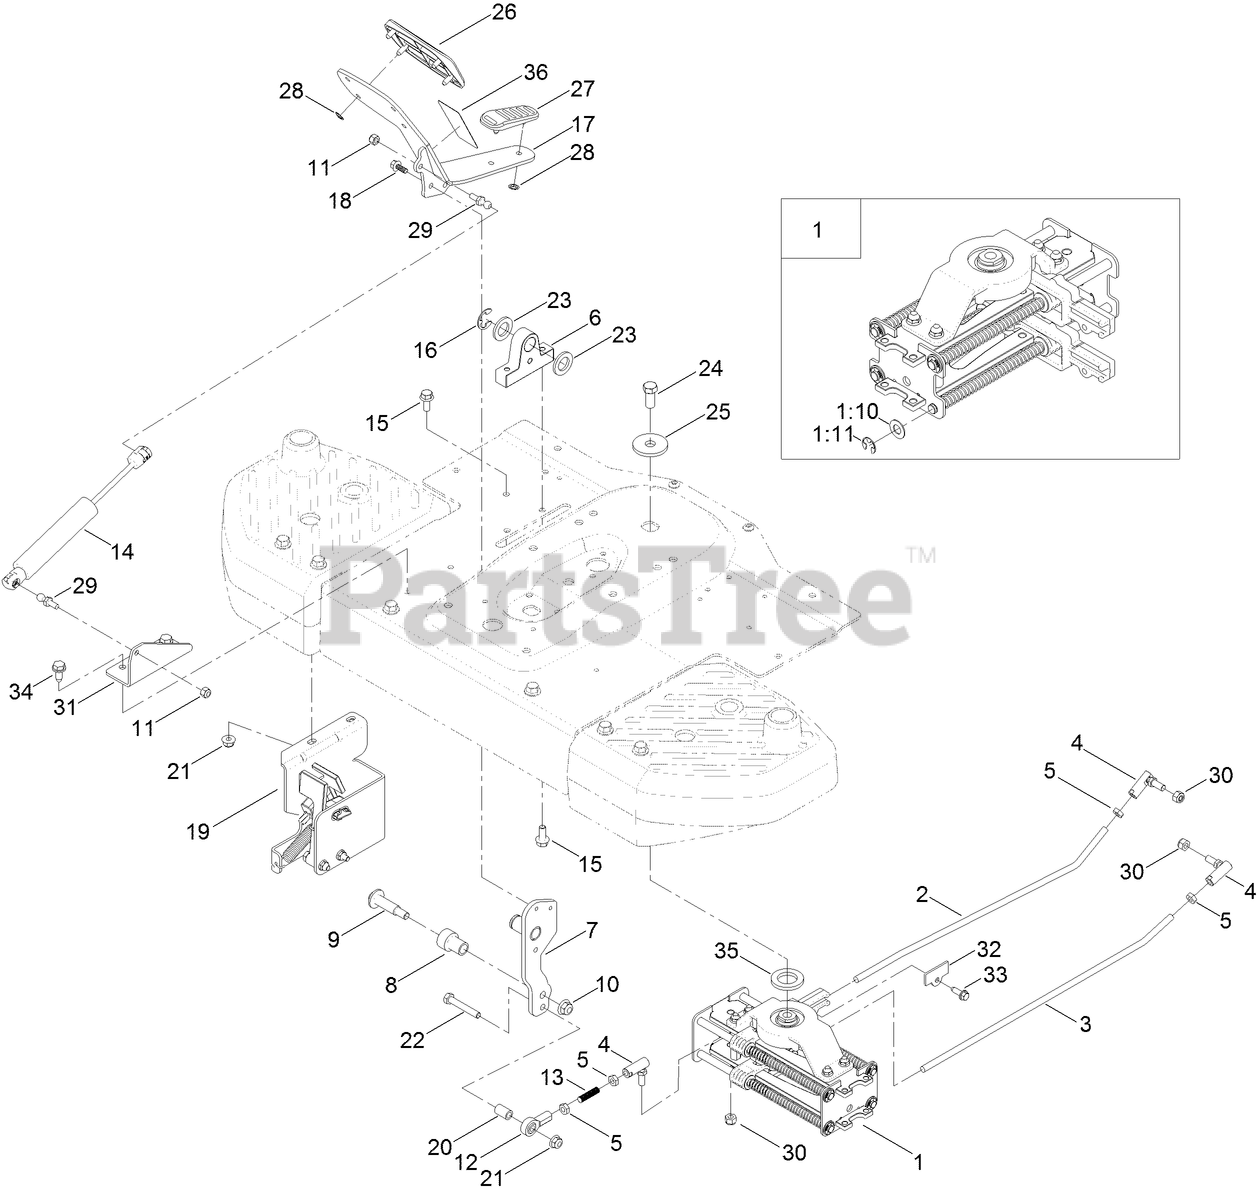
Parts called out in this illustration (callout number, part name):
1	SPEED CONTROL ASM
1:10	WASHER-THRUST
1:11	E-RING
2	ROD-HYDRO, RH
3	ROD-HYDRO, LH
4	BALLJOINT-RH (W/GROMMET)
5	NUT-JAM
6	MOUNT-PEDAL PIVOT
7	PIVOT LEVER ASM
8	ROLLER
10	NUT-HF, NI
11	NUT-LOCK, NI
12	BALLJOINT-RH
13	ROD-THREADED
14	DAMPER-NON CAVITATING
15	SCREW-HHF
16	E-RING
17	PEDAL-TRACTION
18	SCREW-HHF
19	NEUTRAL RETURN ASM
20	SPACER
21	NUT-HF, NI
22	SCREW-HH
23	WASHER
24	SCREW-HH
25	WASHER-THRUST
26	PAD-TOE, HYDRO PEDAL
27	PAD-HEEL, HYDRO PEDAL
28	NUT-PUSH
29	BALL STUD
30	NUT-LOCK
31	BRACKET-DAMPER
32	COVER-END ROD
33	SCREW-HWH, THREAD ROLL
34	SCREW-HWHTF
35	SPACER-BEARING
36	DECAL-RELEASE, BREAK
